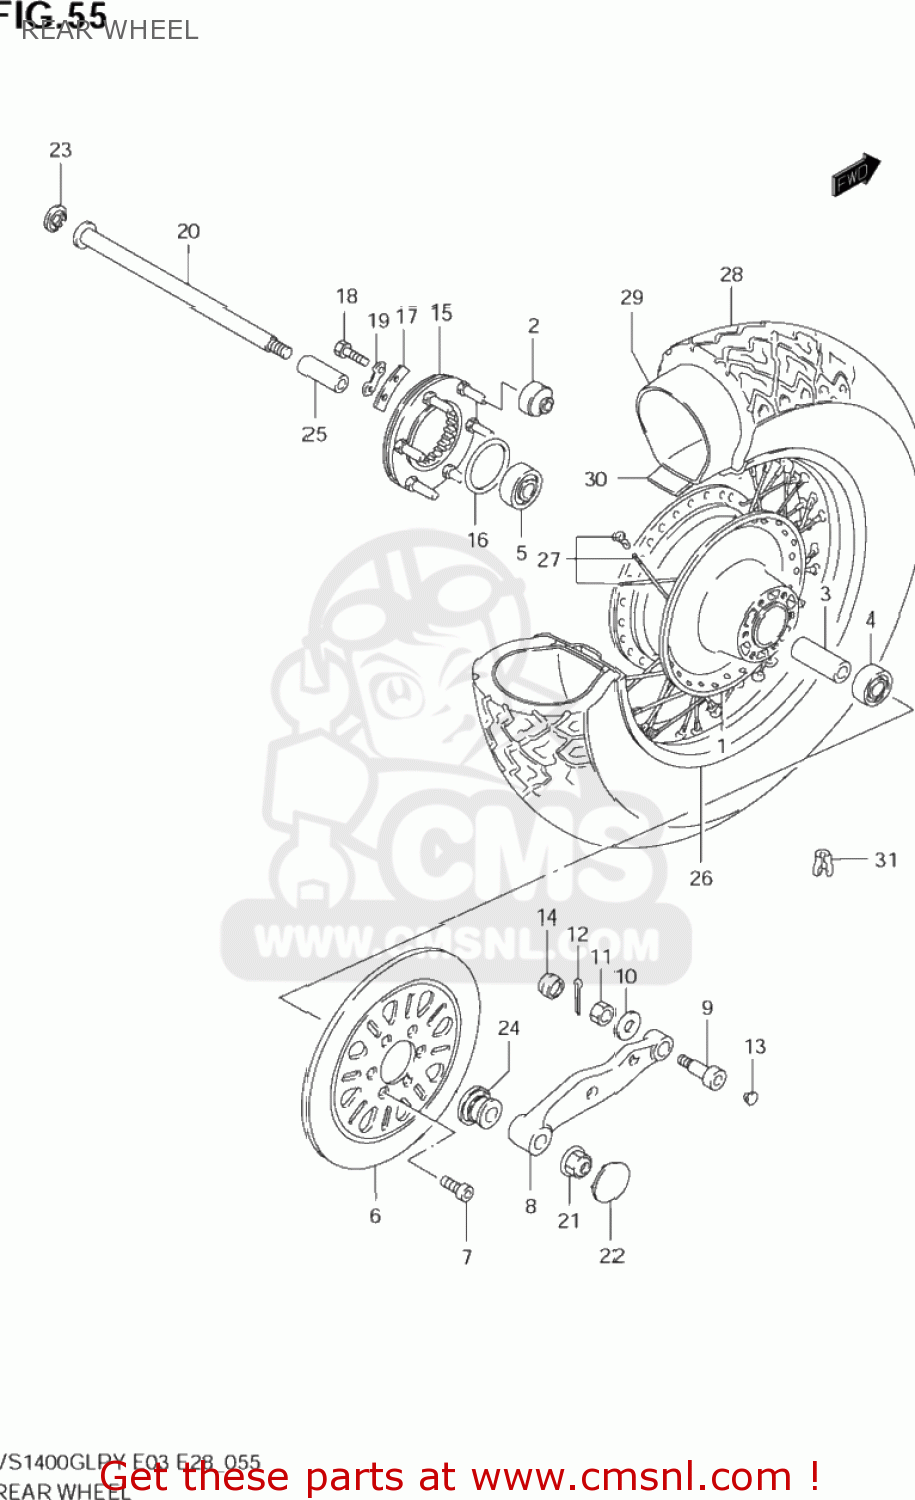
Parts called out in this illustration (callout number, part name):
1	HUB SET,RR
2	BUSH
3	SPACER(17.5X25X113)
4	BEARING
5	BEARING
6	DISC,RR BRAKE
7	BOLT 8X33
8	BRACKET,RR CALIPER
9	PIN,CALIPER BRACKET
10	WASHER(12.5X24X2.6)
11	NUT
12	PIN 20X20
13	CAP(OD:12)
14	CAP
15	JOINT ASSY,RR HUB DRIVEN
16	O RING(D:2.1,ID:65)
17	WASHER,THRUST(T:1.6)
18	BOLT(6X16)
19	WASHER
20	AXLE,RR
21	NUT
22	CAP,RR AXLE,R
23	CAP,RR AXLE,L
24	SPACER,RR AXLE,R
25	SPACER(17.3X25X79.5)
26	RIM,RR WHEEL MT(4.00X1.5)
27	SPOKE SET,RR WHEEL
28	TIRE,RR(170/80 15M/C 77H)
29	TUBE ASSY,WHEEL INNER
30	PROTECTOR, INNER TUBE
31	BALANCER,WHEEL
